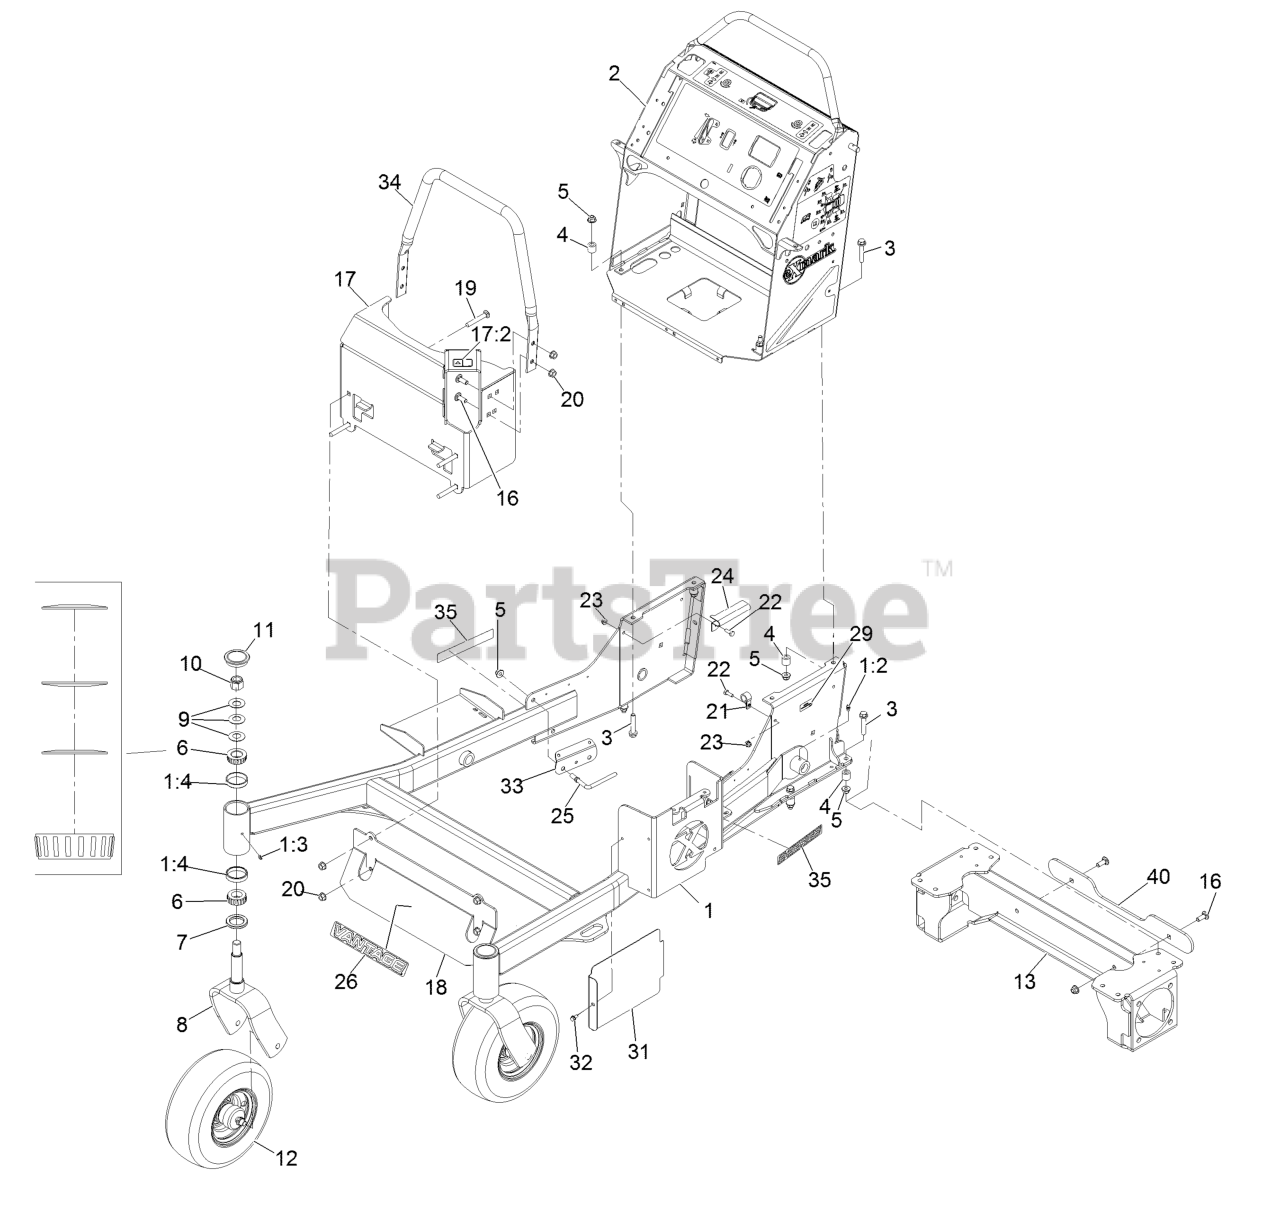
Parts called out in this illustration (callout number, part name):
1	Front Frame ASM
1:2	Zerk 1/4-28 Str Thrd Forming
1:4	Cup-Bearing Tapered Roller
2	ASM-Control Tower
3	Screw-HH Flg 3/8-16 X 2
5	Nut-Nyloc 3/8-16 Flg
6	Cone-Bearing Tapered Roller
7	Seal-Grease
8	Fork-Caster
9	Washer-Spring Disc
10	Nut-Nyloc 3/4-10
11	Cap-Grease
12	Wheel/Tire And Bearing ASM
13	Weld, Motor Frame [black]
16	Bolt-Carriage 3/8-16 X 1
17	ASM, Muffler Guard W/Decal
17:2	Decal-Warning
18	Panel-Guard
19	Bolt-Carriage 3/8-16 X 2 1/2
20	Nut-3/8-16 Flanged Side Lock
21	Clamp-Cable
22	Screw-HH 1/4-20 X 3/4
23	Nut-Nyloc 1/4-20 Flg
24	Bracket-Hose, Fuel
25	Guide-Hose, Support
26	Decal-Vantage Logo
29	Decal-Patent
31	Shield-Heat, Tall
32	Screw-HWH 1/4-20 X 1/2 Taptite
33	Guard-Hose
34	Tube-Guard
35	Decal-S-Series
40	Plate, Bumper Spacer
